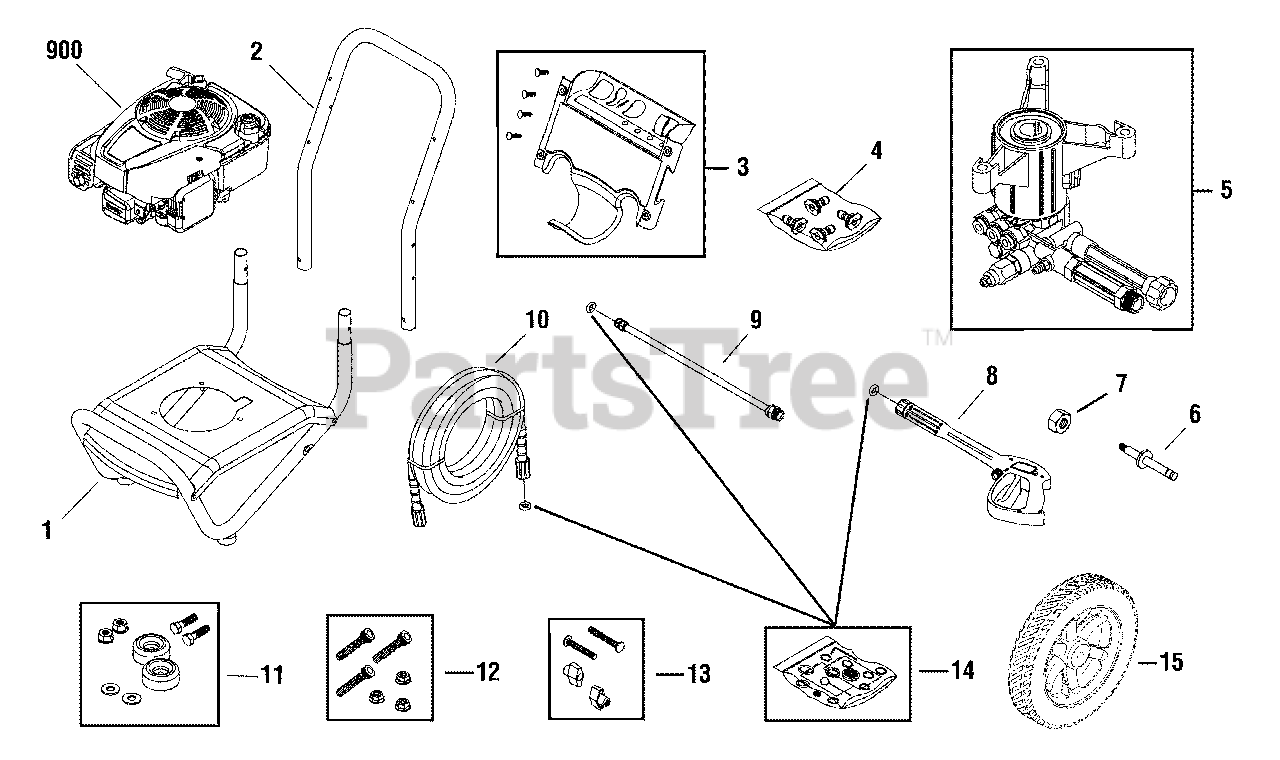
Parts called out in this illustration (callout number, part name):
5	PUMP
7	NUT
8	GUN
9	EXTENSION, QC
10	HOSE
11	MOUNT, Vibration
12	KIT, Hardware Pump Mounting
14	KIT, O-Ring
900	*ENGINE
